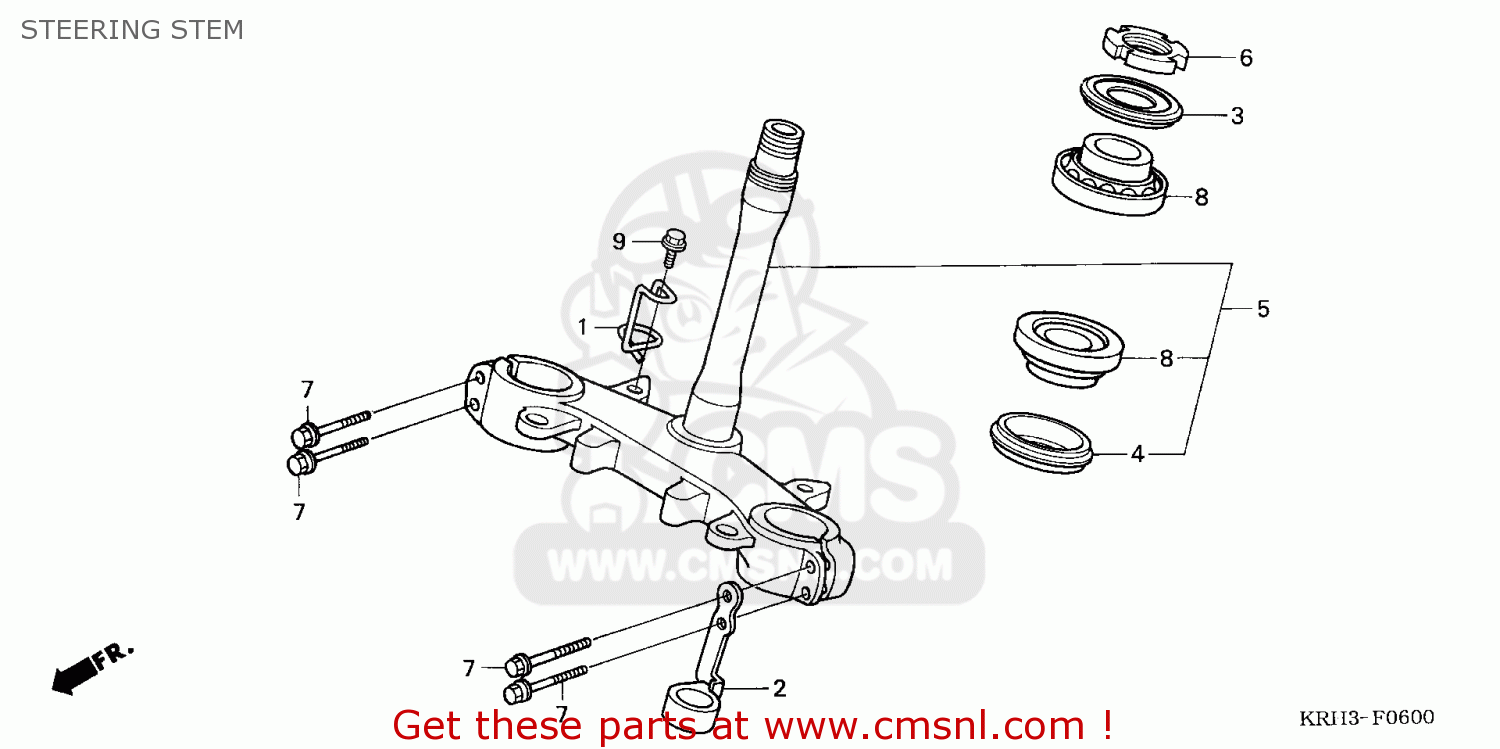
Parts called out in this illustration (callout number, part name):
1	GUIDE,SPDMT CABLE
2	GUIDE COMP,LOWER
3	DUST SEAL,STRG.
4	DUST SEAL,STRG.HD
5	STEM SUB ASSY,STR
6	THREAD,STRG(HEAD
7	BOLT,FALNGE 8X35
8	B/BRG RAD N/COM
